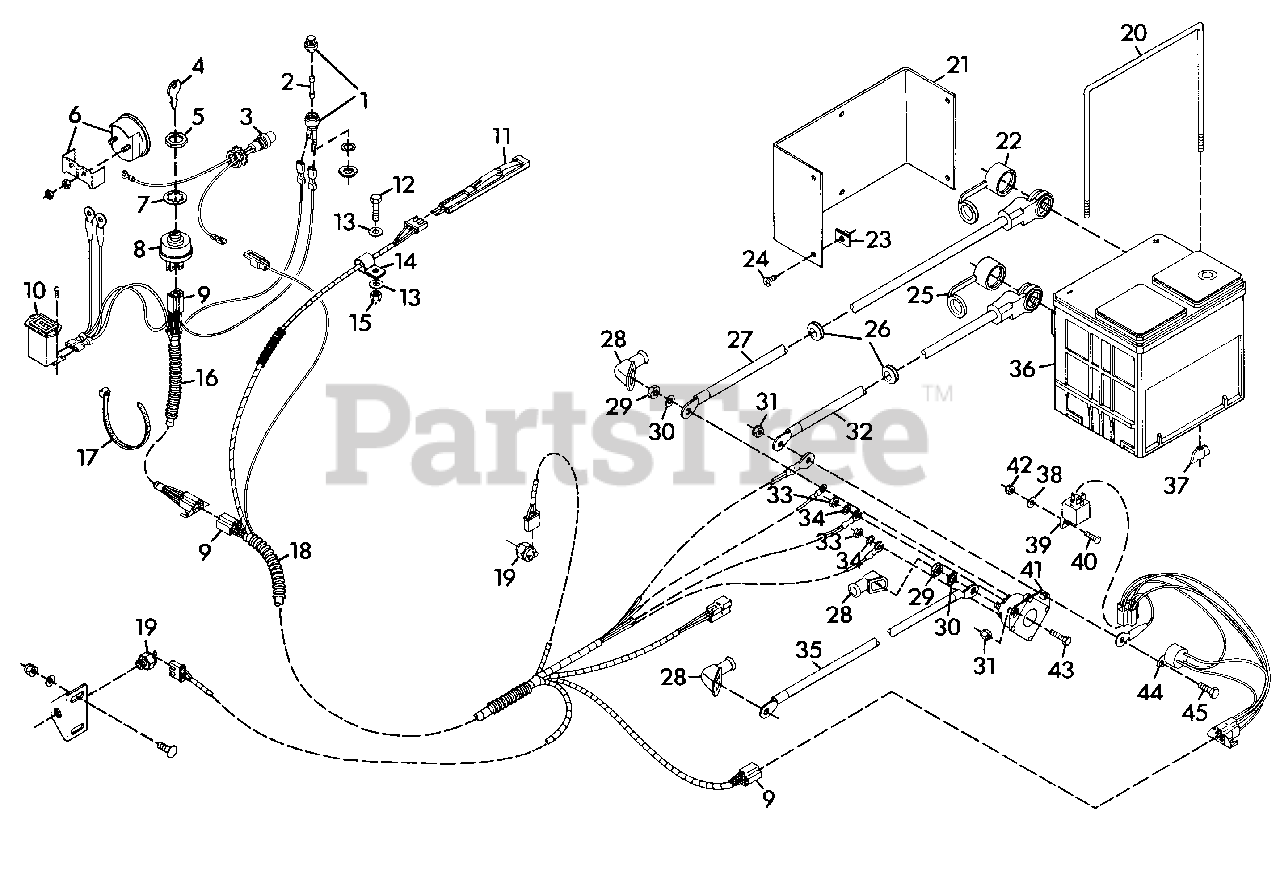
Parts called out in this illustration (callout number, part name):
1	FUSE, PANEL
2	FUSE, 25 AMP
3	LIGHT, INDICATOR
4	KEY, IGNITION SWITCH
5	NUT, JAM 9/16-24
6	GAUGE, VOLTMETER
7	WASHER, LOCK
8	SWITCH, IGNITION
9	CONNECTOR
10	HOURMETER
11	SWITCH, SEAT
12	BOLT, HEX 5/16-18X.875
13	WASHER, FLAT .344X.688X.065
14	CLAMP, NYLON
15	NUT, LOCK 5/16-18
16	HARNESS, WIRING INSTRUMENT PANEL
17	TIE, CABLE
18	HARNESS, WIRING
19	SWITCH, NEUTRAL START
20	ROD, BATTERY
21	GUARD, BATTERY
22	COVER, BATTERY POSITIVE TERMINAL
23	NUT, RETAINER
24	SCREW, MACHINE 1/4-20X.625 RD HD
25	COVER, BATTERY NEGATIVE TERMINAL
26	GROMMET
27	CABLE, ELECTRICAL
28	BOOT, BATTERY CABLE
29	NUT, JAM 5/16-18
30	WASHER, LOCK 5/16 INT. TOOTH
31	NUT, LOCK 1/4-20
32	CABLE, ELECTRICAL
33	NUT, HEX 10-32
34	WASHER, LOCK #10 INT. TOOTH
35	CABLE, STARTER
36	BATTERY, 12 VOLT
37	NUT, WING 1/4-20
38	WASHER, FLAT .188X.438X.049
39	RELAY
40	SCREW, MACH. 10-24X.75 P/HD
41	SWITCH, MAGNETIC
42	NUT, LOCK 10-24
43	BOLT, HEX 1/4-20X1.00
44	MODULE, TIME DELAY
45	BOLT, HEX 1/4-20X1.25
